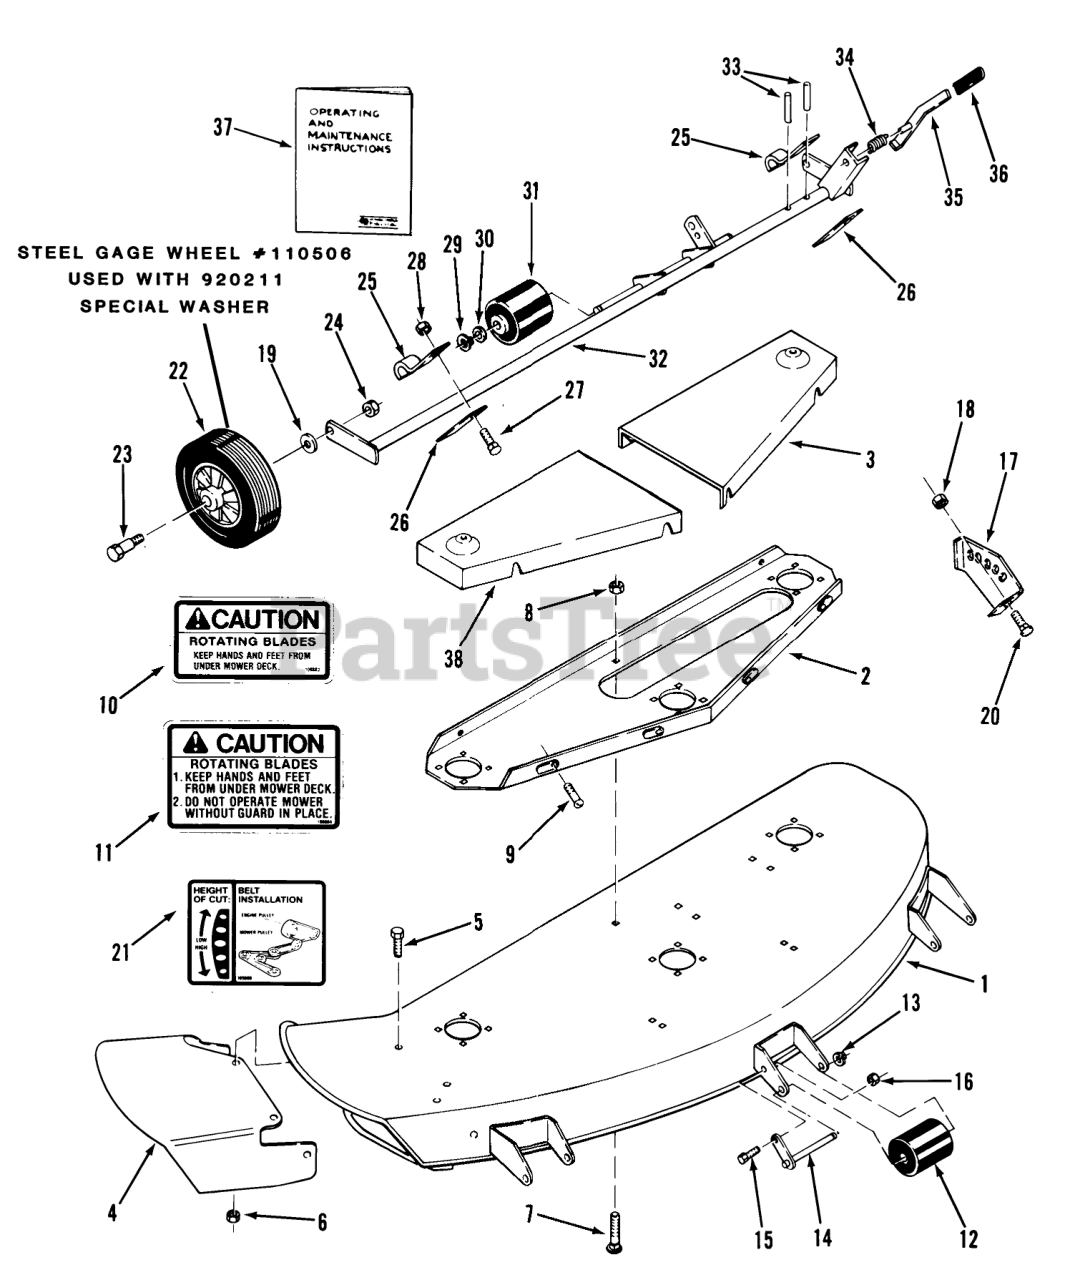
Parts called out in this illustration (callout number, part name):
19	WASHER-FLAT
23	BOLT-SHOULDER
33	PIN-SPIROL
34	SPRING-COMPRESSION
37	Operating Maintenance Instructions
